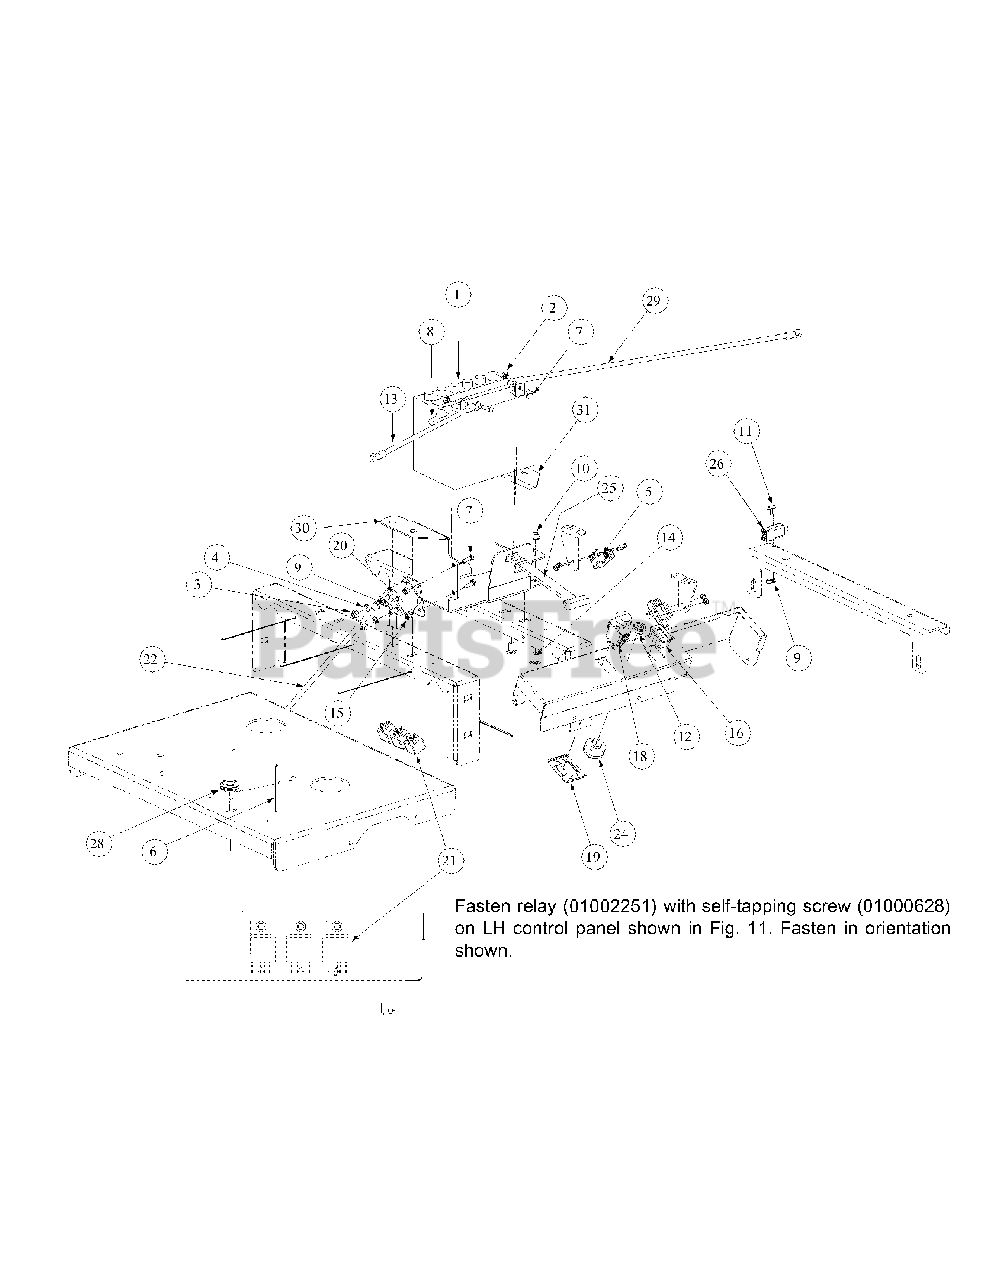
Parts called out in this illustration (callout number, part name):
1	Battery, 12V 225CCA 30 Min
2	Hex Flange Lock Nut, 1/4-20
3	Nylock Nut, 5/16-18
4	Lock Washer, 5/16
5	Switch, Safety
6	Tie, Cable, 3/16 x .05 x 7.4"
7	Screw, Hex, Cap, 1/4-20 x .75
8	Boot, 1" OD Rubber Battery-PST, Red
9	Nut, Lock, Nylon Insert, #10-32
10	Nut, Hex, Flange Lock, 3/8-16
11	Screw, Phillips Head, Machine, 10-32 x 5/8
12	Nut, W/Cap, 5/8-32 Ignition
13	Cable, Battery, Red, 15"
14	Carriage Bolt, 3/8-16 x .75 LG.
15	Lock Nut w/Nylon Insert
16	Meter, Hour
17	Hourmeter, Harness
18	Switch, Electric, PTO
19	Bracket, PTO Switch Retainer
20	Solenoid Magnetic Switch
21	Relay, 12V 40A
22	Cable, Battery Red, 32"
24	Switch, Ignition, 6 Pin
25	Strap, Battery
26	Switch, Plunger
27	Harness Assembly
28	Grommet, .75 ID
29	Cable, Battery Black, 24"
30	Mount Bracket, Battery
31	Mount Bracket, Battery
